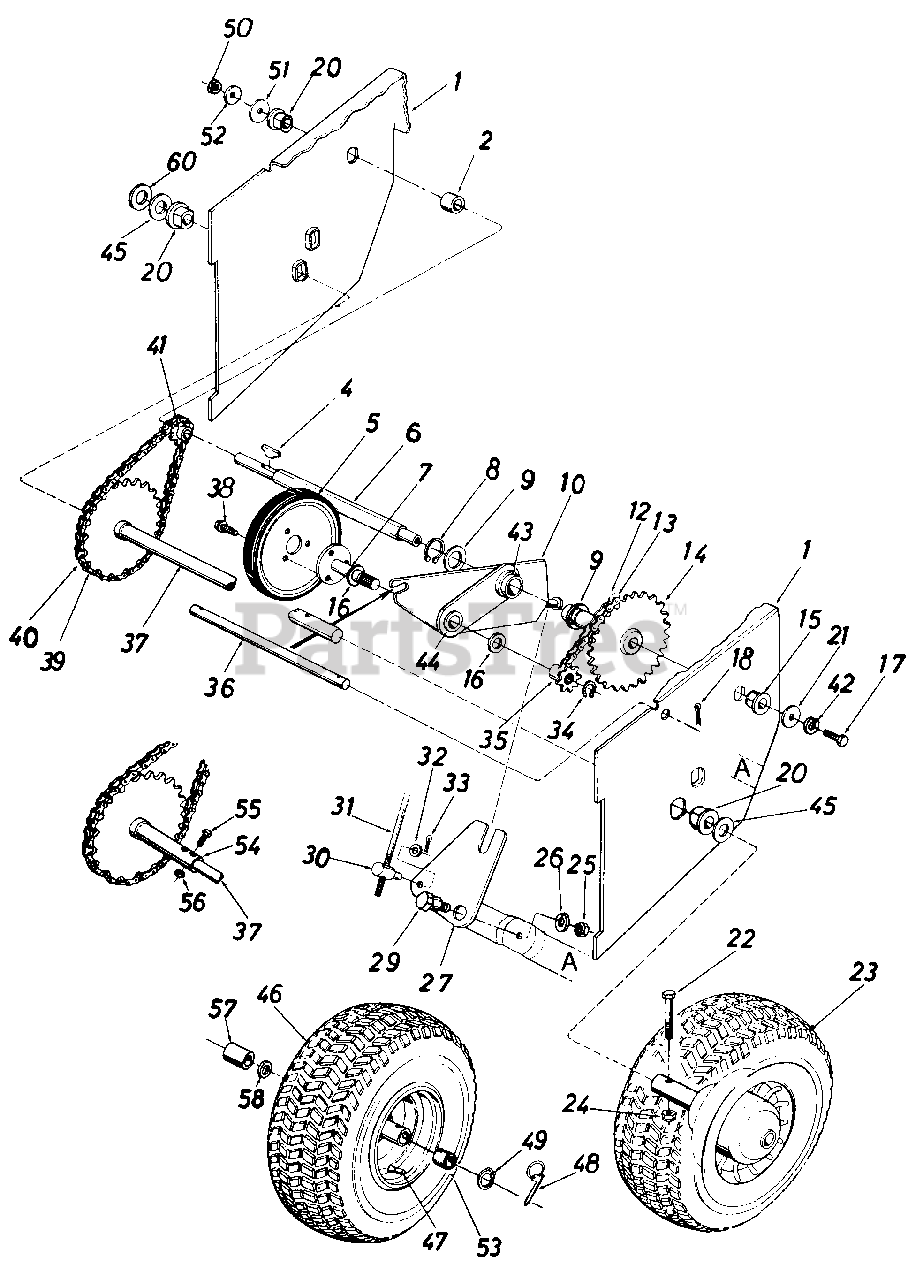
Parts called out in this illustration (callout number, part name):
1	Frame Ass'y.
2	Spacer .50" I.D. x .75" O.D. x.78" Lg.
4	#4 Hi-Pro Key 3/32 x 518" Dia.
5	Friction Wheel Ass'y.
6	Hex Shaft
7	Friction Wheel Mounting Plate Ass'y.
8	Snap Ring 1.00" Dia. Shaft
9	Fl-Wash 1.00" x 1.63" O.D. x 03
10	Sliding Bracket Ass'y.
12	#41 Chain 1/2" Pitch x 35 Links
13	Master Link for #41 Chain
14	32 Teeth Sprocket Ass'y.
15	Hex Flange Brg. .630" I.D.
16	Fl-Wash. .62" I.D. x 1.00" O.D. x .06
17	Hex Lock Bolt 5/16-18 x .62" Lg.
18	Cotter Pin 3/32" Dia. x .75" Lg.
20	Flange Brg. w/Flats .75" I.D.
21	Fl-Wash. .34" I.D. x 1.12" O.D. x .125
22	Hex Bolt 5/16-24 x 1.50" Lg.
23	Wheel Ass'y.
24	Hex Ins. Jam L-Nut 5/16-24 Thd.
25	Hex Jam Nut 3/8-16 Thd.
26	L-Wash. 3/8" I.D.
27	Shifting Linkage Bracket
29	Shld. Bolt .625" Dia. x .170" Lg.
30	Adjustment Ferrule
31	Shifting Rod 5/16" Dia. x 32.50" Lg.
32	Fl-Wash. .34" I.D. x .64" O.D. x .06
33	Cotter Pin 3/32" Dia. x .75" Lg.
34	Snap Ring .562" Dia. Shaft
35	Sprocket 7 Teeth x .50" Pitch
36	Shaft .50" Dia. x 9.50" Lg.
37	28 Teeth Wheel Axle Ass'y.
38	Hex Wash. Hd. Self-Tap Scr. 5/16-24 x .50" Lg.
39	#41 Chain 1/2" Pitch x 43 Links
40	Master Link for #41 Chain
41	8 Teeth Center Sprocket
42	L-Wash. 5/16" I.D.
43	Bearing
44	Bronze Bearing
45	Fl-Wash. .76" I.D. x 1.49 O.D.
46	Wheel Assembly
47	Air Valve
48	Klick Pin
49	Snap Ring .75 Dia.
50	Hex Ins. L-Nut 1/2-20 Thd.
51	Fl-Wash. .53 I.D. x 1.25 O.D. x .10
52	Bell-Wash. .50 I.D. x 1.0 O.D. x .075
53	Sleeve Brg.
54	32 Teeth Sprocket Hub Ass'y.
55	Hex Bolt 1/4-28 x 1.5"
56	Hex L-Nut 1/4-28 Thd.
57	Spacer
58	Fl-Washer
60	Fl-Washer
